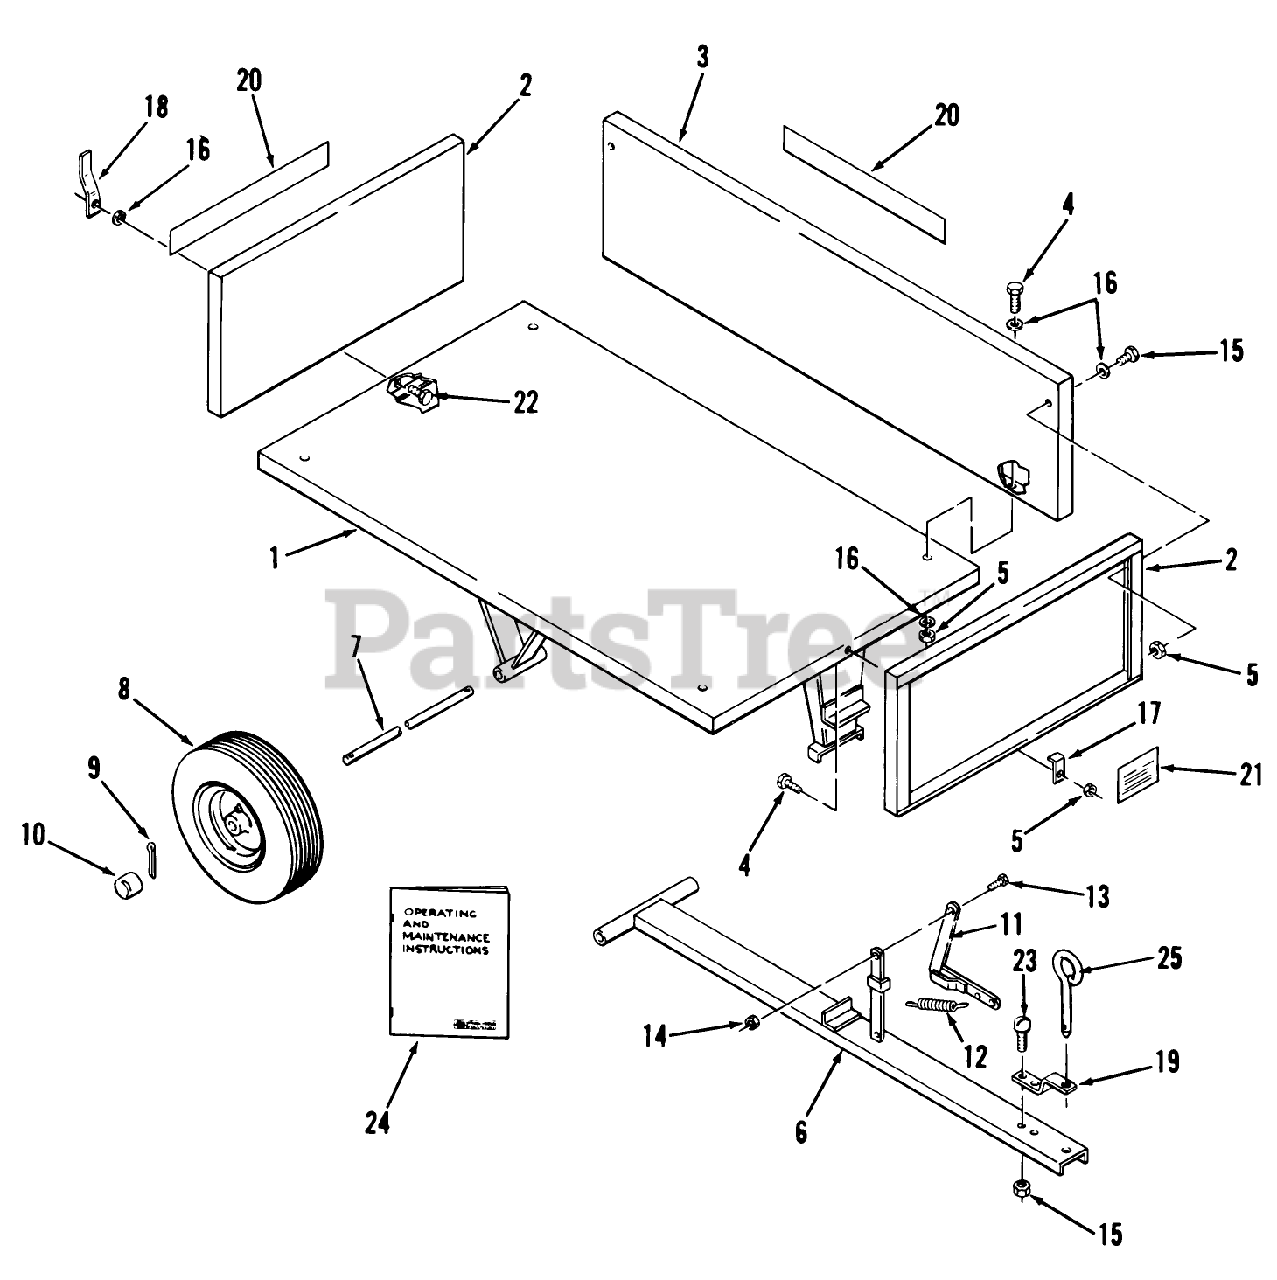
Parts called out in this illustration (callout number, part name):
1	Bed Assembly
21	Weight Limit Decal
24	MANUAL-OPERATOR
25	PIN-TOOL
